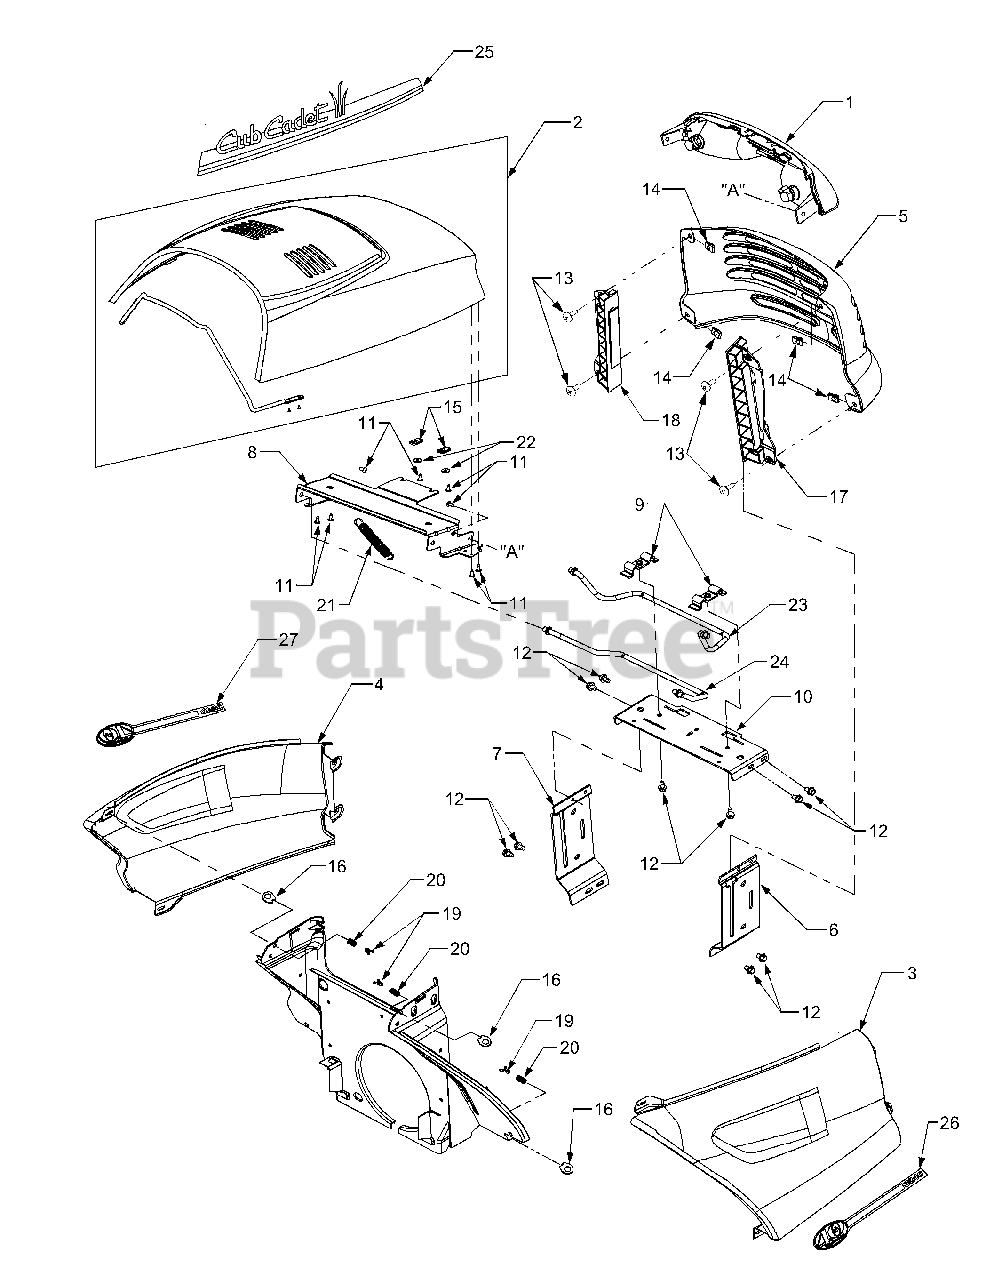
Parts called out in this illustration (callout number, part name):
1	Headlight Assembly (Lens glued to reflector)
2	Hood w/Support Rod Assembly
3	Side Panel, RH
4	Side Panel, LH
5	Grille, Series 3000
6	Support, Grille - RH
7	Support, Grille - LH
8	Bracket, Upper Hood
9	Bracket, Rod Retainer
10	Support, Hood
11	Screw, Truss Hd, Tapp, #10-16 x .5
12	Screw, Hex Wash. Hd. Tapp 5/16-18 x .5
13	Screw, Phil. Pan Hd. 1/4-20 x .75
14	Nut, U Type Speed, 1/4-20
15	Nut, U-type Speed, #10
16	Latch, 1/4 Turn
17	Mount, Side Panel/Grille RH
18	Mount, Side Panel/Grille LH
19	Clip, Spring
20	Spring, Compression
21	Spring, Extension
22	Washer, Flat, .194 x .62 x .063
23	Rod, Upper Hood
24	Rod, Lower Hood
25	Graphic, Hood - RH
26	Graphic, 3240 - RH
27	Graphic, 3240 - LH
